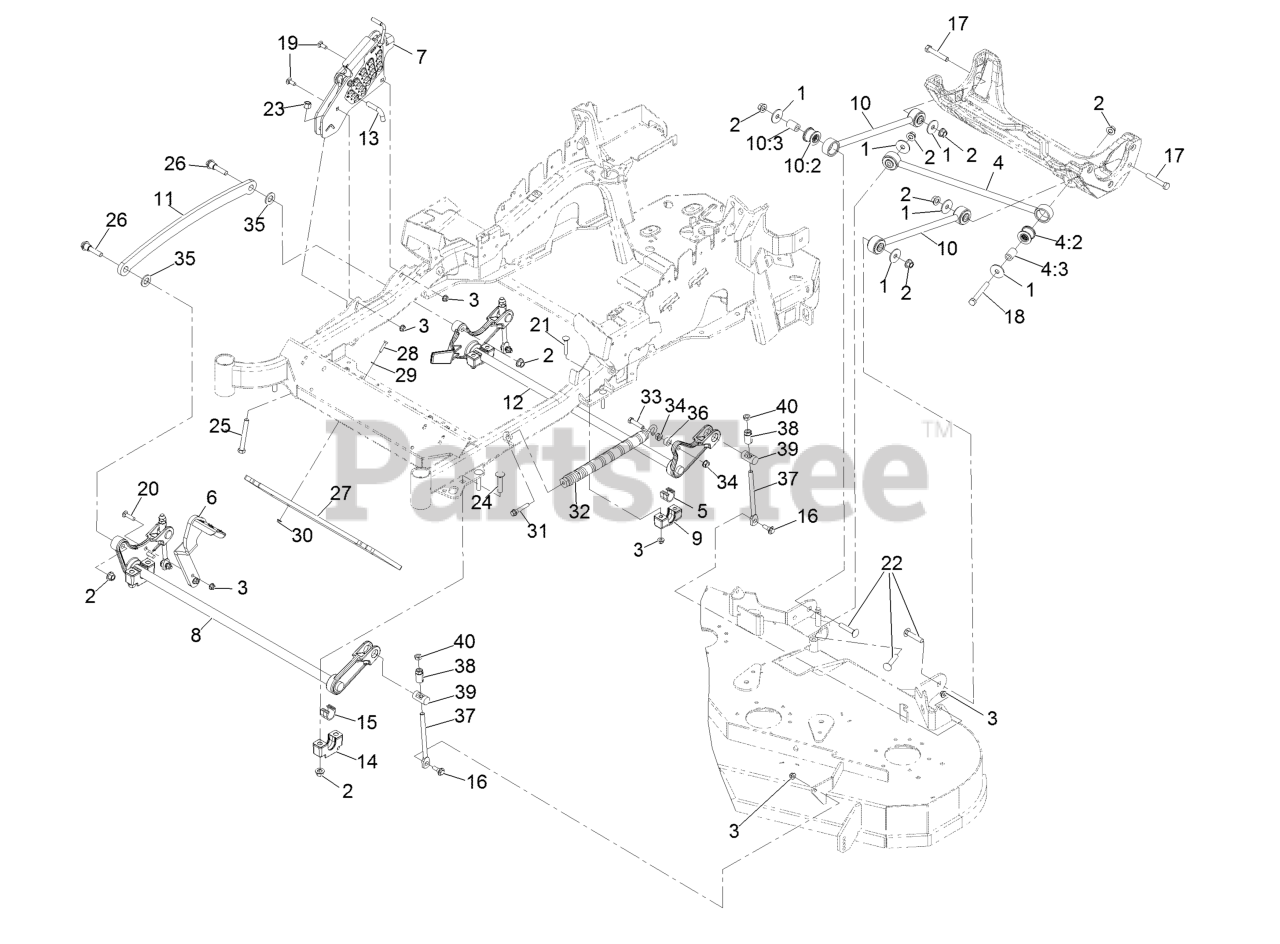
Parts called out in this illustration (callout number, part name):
1	WASHER-THRUST
2	Nut-Lock 1/2-13
3	NUT-HF, NI
4	PANHARD ROD ASM
4:2	BUSHING-SUSPENSION, RUBBER
5	BEARING-CROSS SHAFT, REAR
6	LEVER-FOOT
7	HOC ASM
8	DECKLIFT-FRONT
9	SUPPORT-CROSS SHAFT, BEARING REAR
10	DECK STRUT ASM
10:2	BUSHING-SUSPENSION, RUBBER
11	LINK-LIFT, DECK
12	LIFT-DECK, REAR
13	PIN-HOC
14	SUPPORT-CROSS SHAFT, BEARING
15	BEARING-CROSS SHAFT, FRON
16	SCREW-SHOULDER, HHF
17	SCREW-HH
18	SCREW-HH
19	BOLT-CARR
20	SCREW-CARR
21	Bolt-Carriage 3/8-16 X 2 1/4
22	SCREW-CARR
23	NUT-LOCK, NI
24	Bolt-Carriage 1/2-13 X 2 1/2 Spl Neck
25	BOLT-TAP
26	SCREW-HHF, SHOULDER
27	WEIGHT-TOE BOARD
28	SCREW-HH
29	WASHER-FLAT
31	BOLT-SHOULDER
32	SPRING-EXTENSION
33	SCREW-HH
35	WASHER-FLAT
37	LINK-ADJUSTER, DECK LIFT
38	ADJUSTER-LIFT, DECK
39	TRUNNION
40	NUT-JAM
